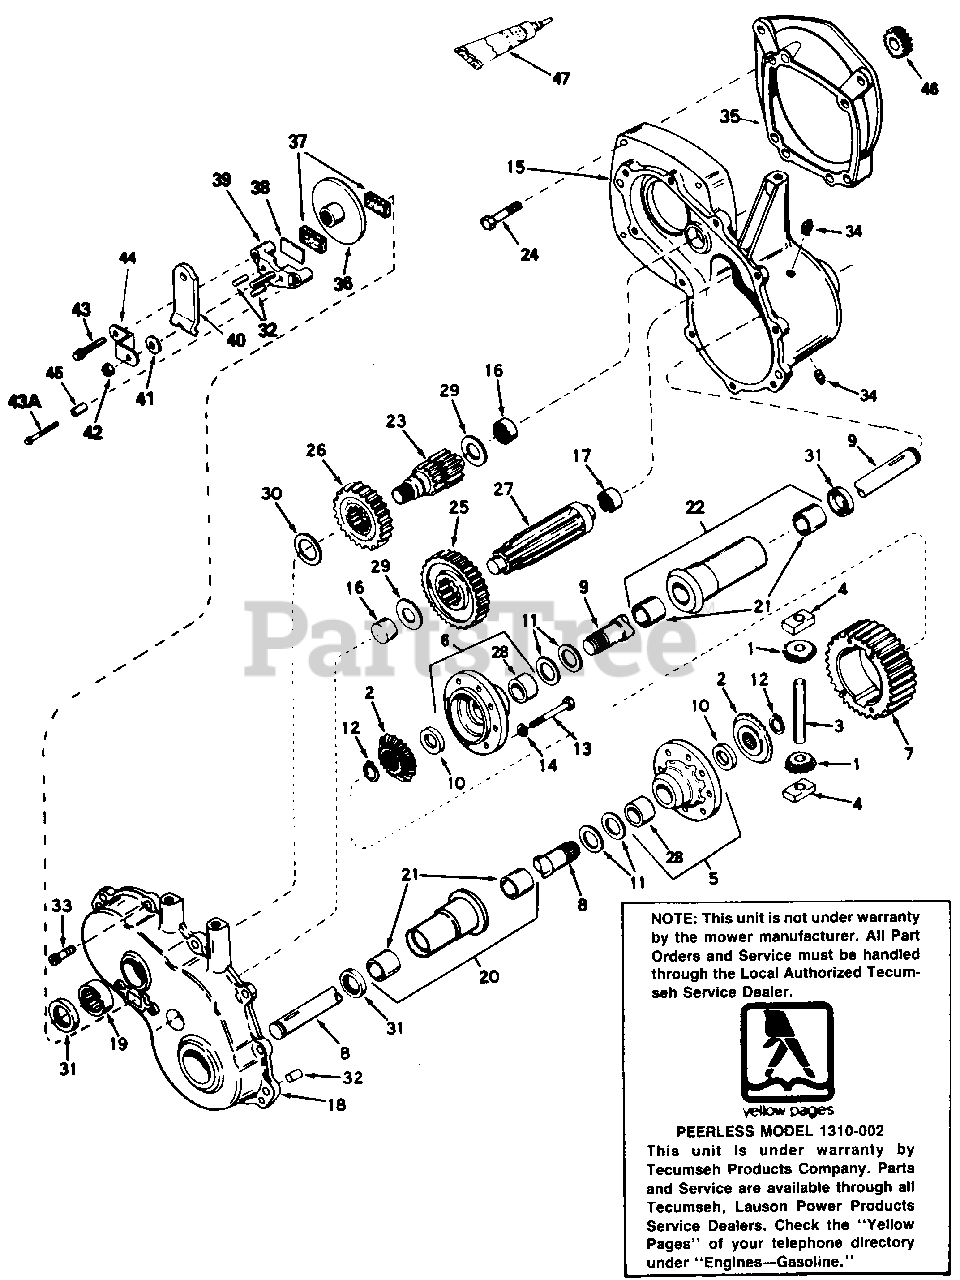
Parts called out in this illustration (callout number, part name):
1	Pinion, Bevel
2	Gear, Bevel
3	Pin, Drive
4	Block, Drive
5	Carrier Ass'y., Differential
6	Carrier Ass'y., Differential
7	Gear, Ring
8	Axle (13-1/16" Long)
9	Axle (19-1/8" Long)
10	Washer
11	Washer, Thrust
12	Ring, Snap
13	Screw, Hex Hd., 1/4-20 x 21/4
14	Lock Washer, 1/4"
15	Case Ass'y.
16	Bearing, Needle
17	Bearing, Needle
18	Cover Ass'y.
19	Bearing, Needle
20	Housing & Bushing Ass'y. (6-518" Long)
21	Bushing
22	Housing & Bushing Ass'y.
23	Shaft, Brake
24	Screw, Hex Hd., 3/8-16 x 2
25	Gear, Output
26	Gear, Idler
27	Shaft, Output
28	Bushing
29	Washer
30	Washer
31	Seal, Oil
32	Pin, Dowel
33	Screw, Hex Washer Hd. Thread Forming, 1/4-20 x 1
34	Plug, Pipe
35	Plate, Adapter
36	Disc, Brake
37	Pad, Brake
38	Plate, Brake Pad
39	Holder, Brake Pad
40	Lever, Brake
41	Washer, Flat
42	Lock Nut, 5/16-24
43	Screw, Flanged Hex Ha. Thread Forming, 1/4 20 x 1 1/4
43A	Screw, Flanged Hex Hd. Thread Forming, 1/4-20 x 2-1/4
44	Bracket
45	Spacer
46	Gear, Spur (18 Teeth)
47	Gasket Eliminator
